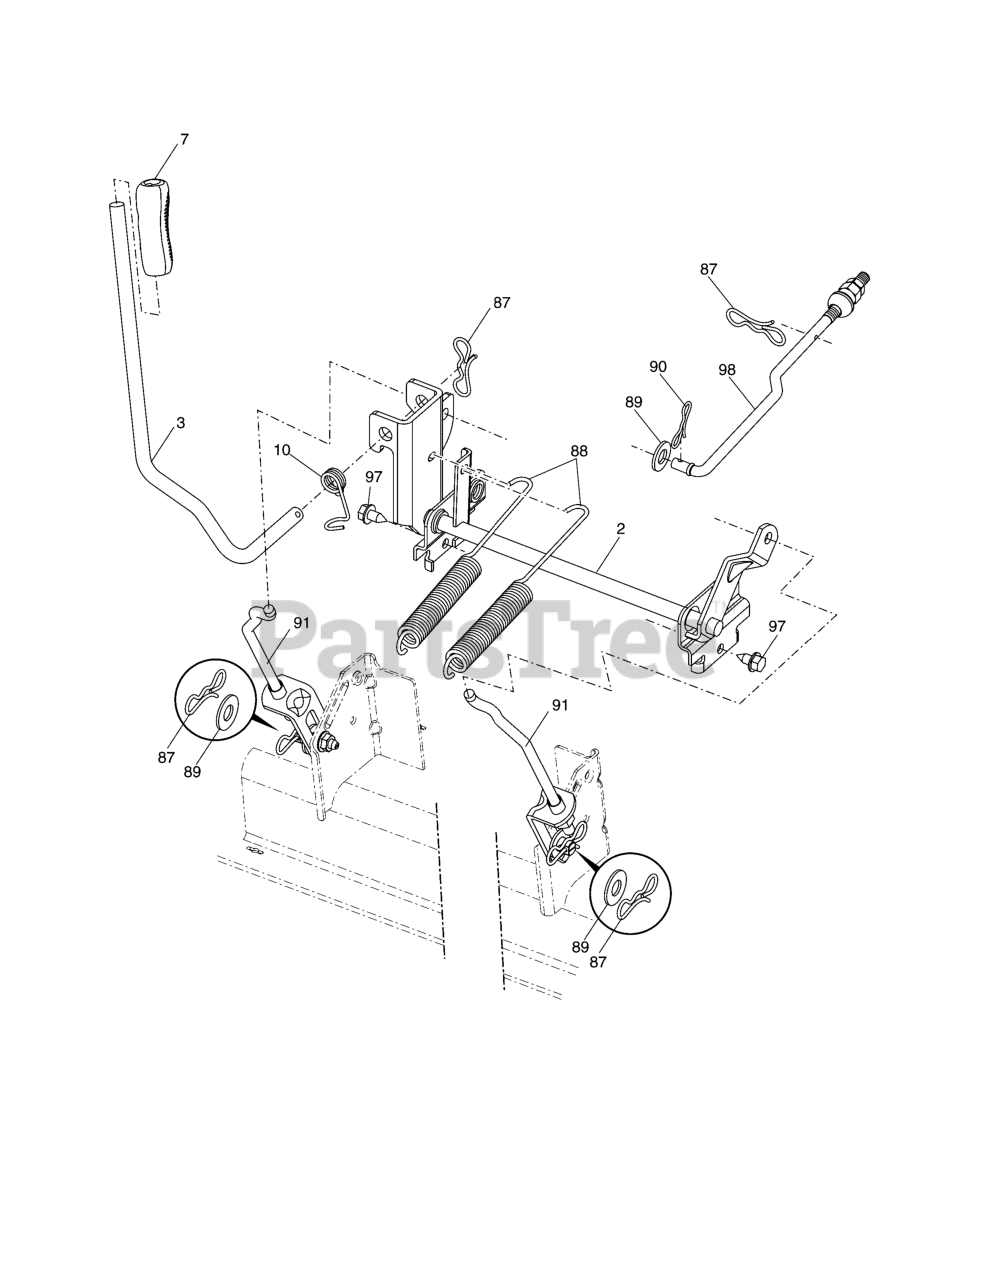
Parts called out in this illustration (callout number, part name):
2	Shaft Asm., Cross Lift
3	Lever Asm., Lift
7	Grip, Lever
10	Spring Torsion
87	Pin Cotter 7/16 Bow Tie Lock
88	Spring Lift Assist
89	Washer Clear Zinc
90	Pin Cotter 5/16 Bow Tie Lock
91	Link Lift Susp Mower Rear
97	Screw 3/8-16 x .75 Smgml Tap/R.Z
98	Link Lift Susp. Front Mower
